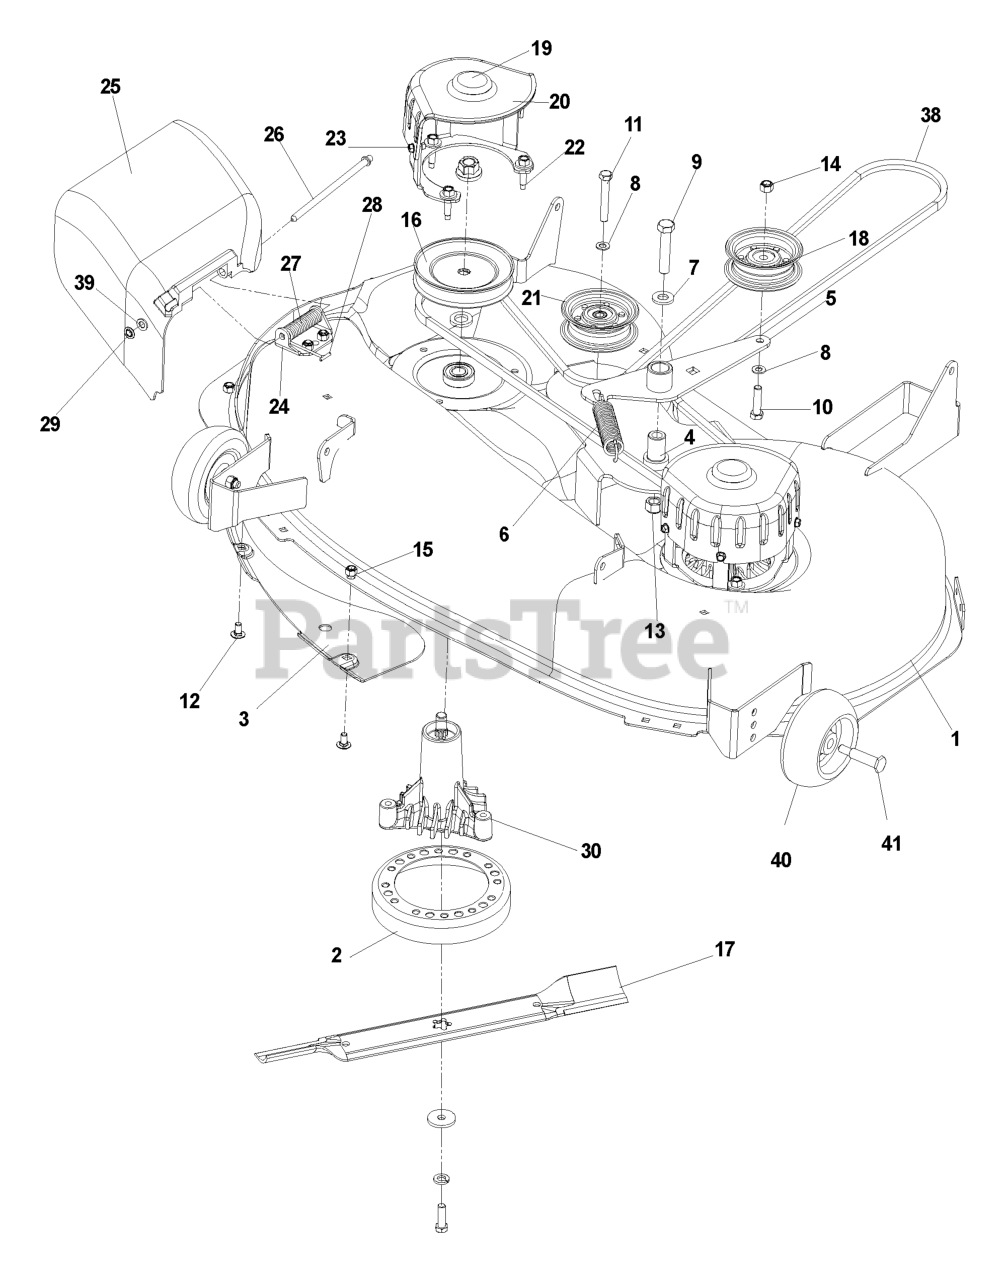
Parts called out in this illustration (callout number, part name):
1	DECK W/DECALS 42" ORANGE
2	STRIPPER-ROUND-UNIVERSAL
3	BAFFLE VORTEX 42
4	IDLER SPINDLE
5	DECK IDLER ARM WELDMENT
7	WASHER 1/2" FLAT
8	WASHER 3/8 SAE FLAT
9	HCS 1/2C X 2 3/4
10	HCS 3/8C X 1 1/2
11	HCS 3/8C X 2 1/2
12	CARRIAGE BOLT 5/16C X 5/8"
13	NUT 1/2-13 HEX NYLOC ZD
14	NUT 3/8-16 NYLOC
15	NUT 5/16 NYLOC
16	PULLEY, MANDREL
17	BLADE 42" MULCHING STD
18	PULLEY, IDLER, SHORT
19	SPINDLE COVER
20	SPINDLE COVER ANCHOR
21	IDLER PULLEY ASM
22	WASHER HEAD SCREW
23	SCREW 1/4 X 5/8
24	BRACKET DEFLECTOR MOWER 42
25	SHEILD DEFLECTOR
26	ROD, HINGE
27	SPRING, TORSION DEFLECTOR
28	CAP-SLEEVE
29	PUSH NUT
30	SPINDLE, MANDREL ASM
38	BELT, V MOWER DECK 42"
39	WASHER, 11/32 X 5/8 X 16 GA
40	WHEEL GUAGE
41	BOLT, SHOULDER
